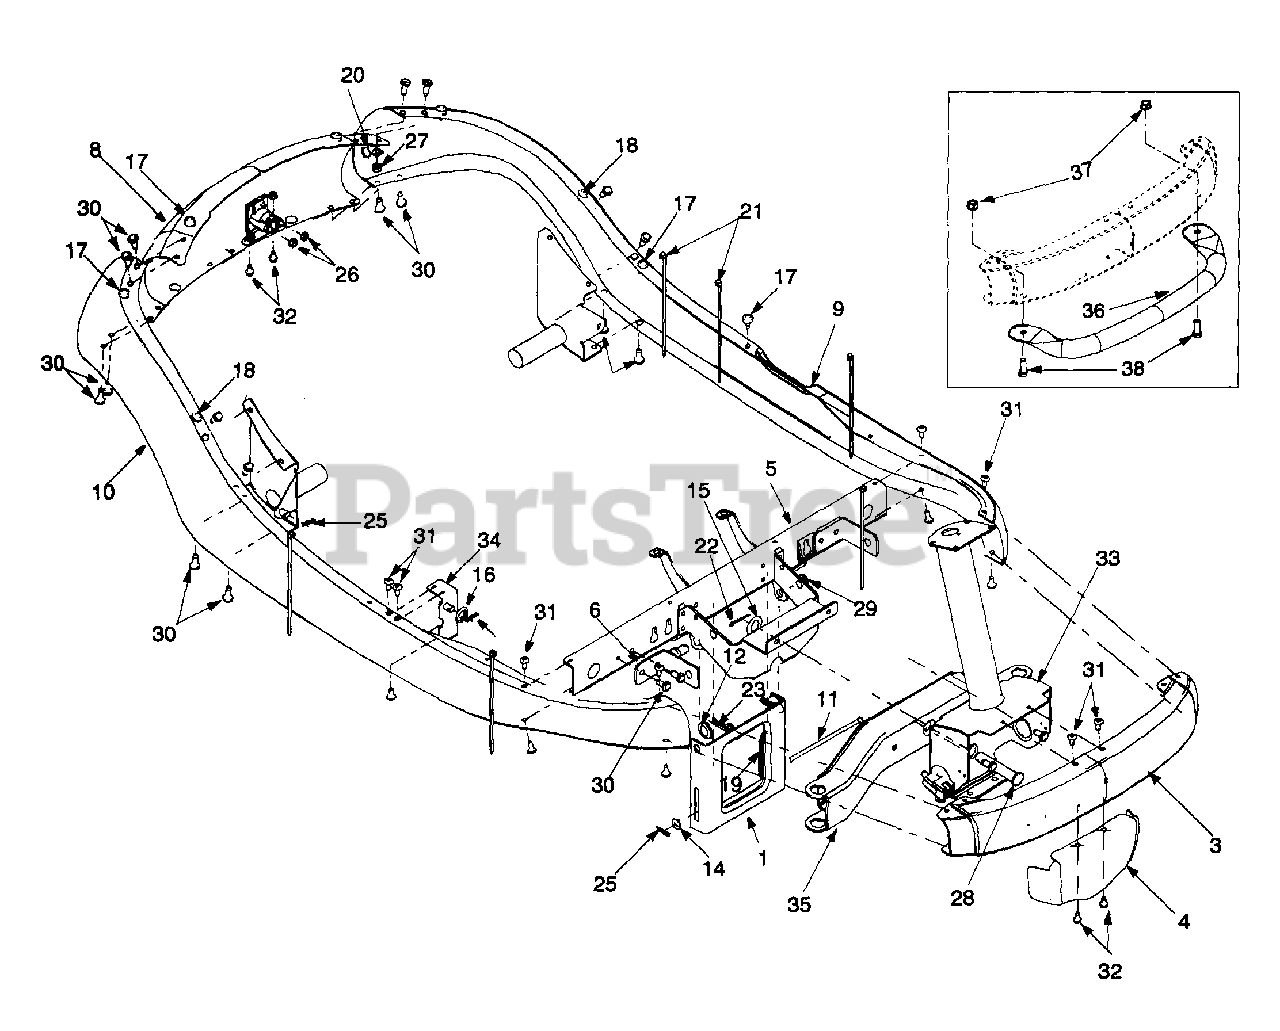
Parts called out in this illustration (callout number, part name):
12	Flat Washer .531 X 1.062 X .134
14	Flat Washer 5/16
15	Flat Washer .64 I.D. X 1.24 X .06
16	Flat Washer 3/8 X 1.00 X .030
17	Rubber Bumper
18	Rubber Bumper
19	Extension Spring
20	Clamp: 9/16 dia.
21	Cable Tie
22	Hairpin Clip
23	Hairpin Clip
25	Hairpin Clip
26	Hex Nut
27	Hex Nut 1/4-20
28	Clevis Pin
29	Lift Bracket Pin
30	TT Screw 5/16-18 x .75
31	Torx Mach. AB Scr. 1/4-14 x 0.625"
32	Hex TT Screw 1/4-20
37	Lock Nut 3/8-16
38	Hex Bolt 3/8-16 x 1.0" Gr. 5
